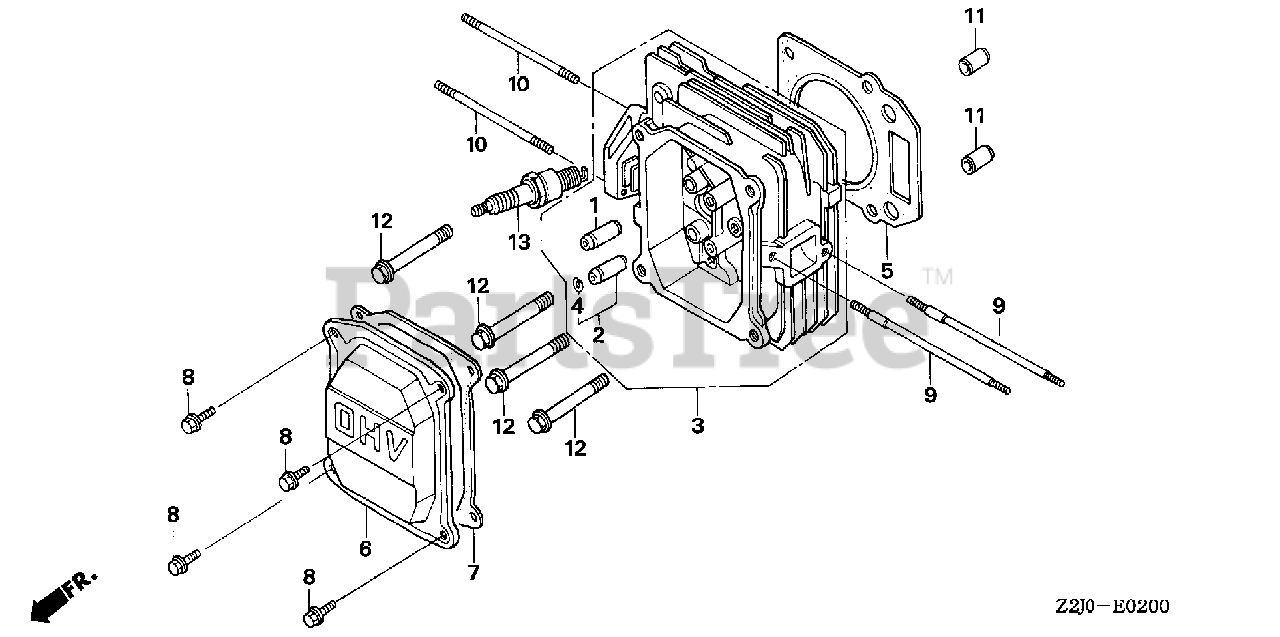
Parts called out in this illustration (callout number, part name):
1	GUIDE, VALVE (OVER SIZE)
2	GUIDE, EX. VALVE (OVER SIZE)
3	CYLINDER HEAD
4	CLIP, VALVE GUIDE
5	GASKET, CYLINDER HEAD
6	COVER, HEAD
7	GASKET, HEAD COVER
8	BOLT, FLANGE (6X12) (CT200)
9	BOLT, STUD (6X109)
10	BOLT, STUD (6X85)
11	PIN, DOWEL (10X16)
12	BOLT, FLANGE (8X50)
13	SPARK PLUG (BPR4ES) (NGK)
13	SPARK PLUG (W14EPR-U) (DENSO)
13	SPARK PLUG (BPR5ES) (NGK)
13	SPARK PLUG (W16EPR-U) (DENSO)
13	SPARK PLUG (BPR6ES) (NGK)
13	SPARK PLUG (W20EPR-U) (DENSO)
